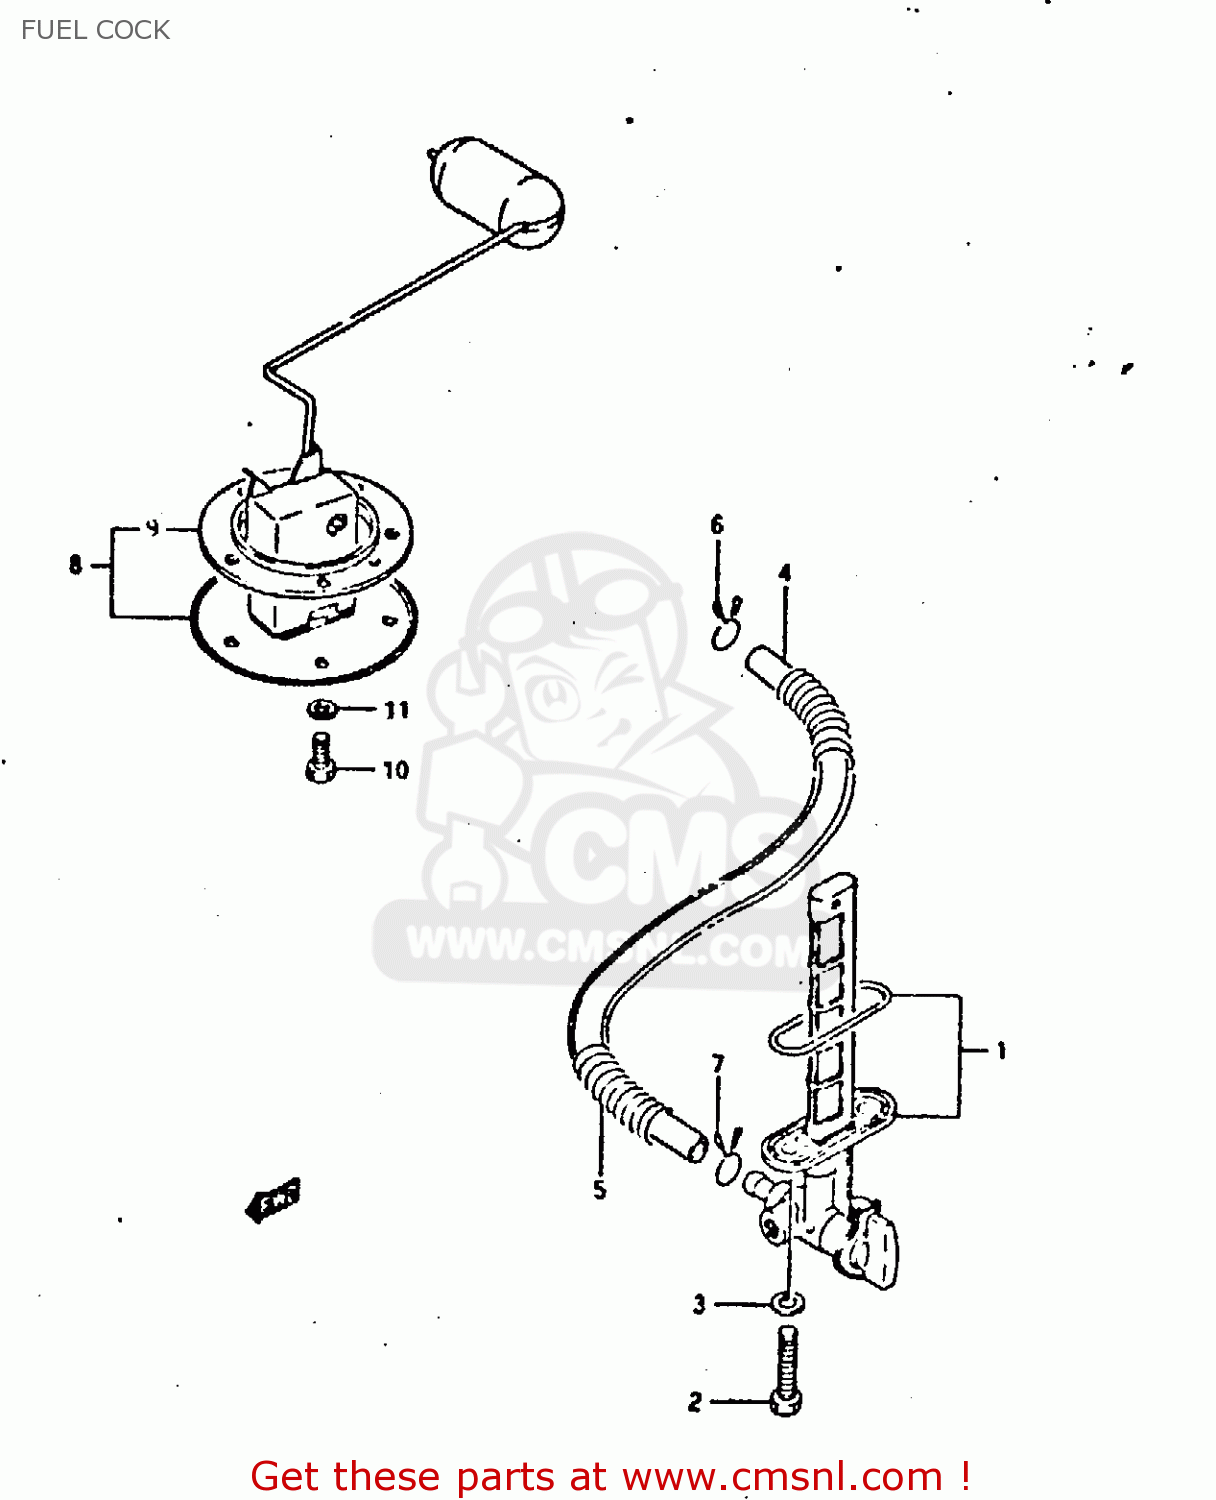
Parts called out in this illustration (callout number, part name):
1	COCK ASSY,FUEL
2	BOLT(6X20)
3	GASKET
4	HOSE
5	SPRING
6	CLIP
7	CLIP
9	GASKET,FUEL LEVEL GAUGE (NAS)
10	BOLT
11	LOCK WASHER
